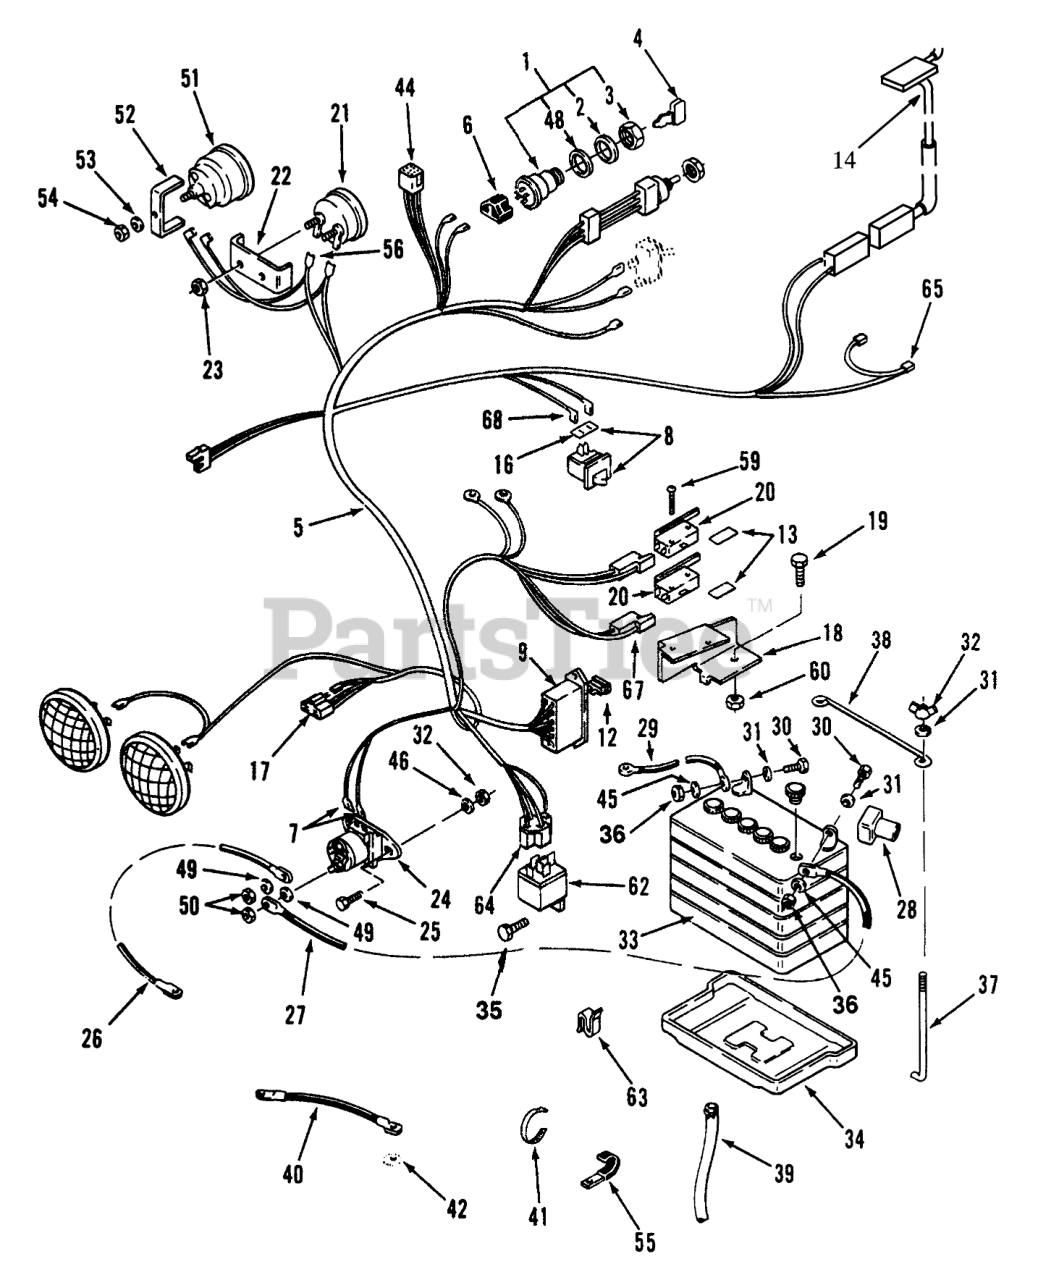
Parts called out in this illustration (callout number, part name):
1	Switch-Ignition (Incl. Ref. #6, 7, 9, 17, 44 & 64-66)
2	LOCKWASHER
4	KEY-IGNITION
5	WIRING-HARNESS & DIA
6	CONNECTOR BODY ELECT
7	TERMINAL 10
8	Switch-Clutch Interlock, (Incl. Ref #16)
9	FUSE-HOLDER 4 WAY
12	FUSE-BLADE, 15 AMP
13	BARRIER - SWITCH
14	SWITCH-SEAT
16	SHIELD-DIRT SPST
17	5-CONTACT CONN BODY
18	BRACKET-SWITCH
19	Bolt
20	SWITCH
21	VOLTMETER
22	CLAMP-MOUNTING
23	HEX NUT 10-32 E.S.
24	SOLENOID
25	Screw
26	ASSY WIRE
27	CABLE-BLACK
28	Boot
29	ASSY WIRE
30	SCREW-HH
31	WASHER-FLAT
32	Nut
33	Battery
34	TRAY-BATTERY
37	HOOK-BATTERY RETAIN
38	HOLDDOWN-BATTERY
39	TUBE-21" BATTERY DRAIN
40	WIRE GROUND
41	PLASTIC TIE
42	WASHER-LOCK, INTERNAL
44	Terminal
45	WASHER-LOCK
48	Washer
49	WASHER-LOCK
50	NUT-JAM
51	Meter-Hour (Incl. Ref. #52-54)
52	BRKT-GAUGE MOUNTING
53	Lockwasher
54	Hex Nut
55	CLIP
59	Screw
60	NUT HEX 4-40 ELAST
62	RELAY
63	CLIP-CABLE
64	TERMINAL 10
65	Sur-Plug
68	Terminal
